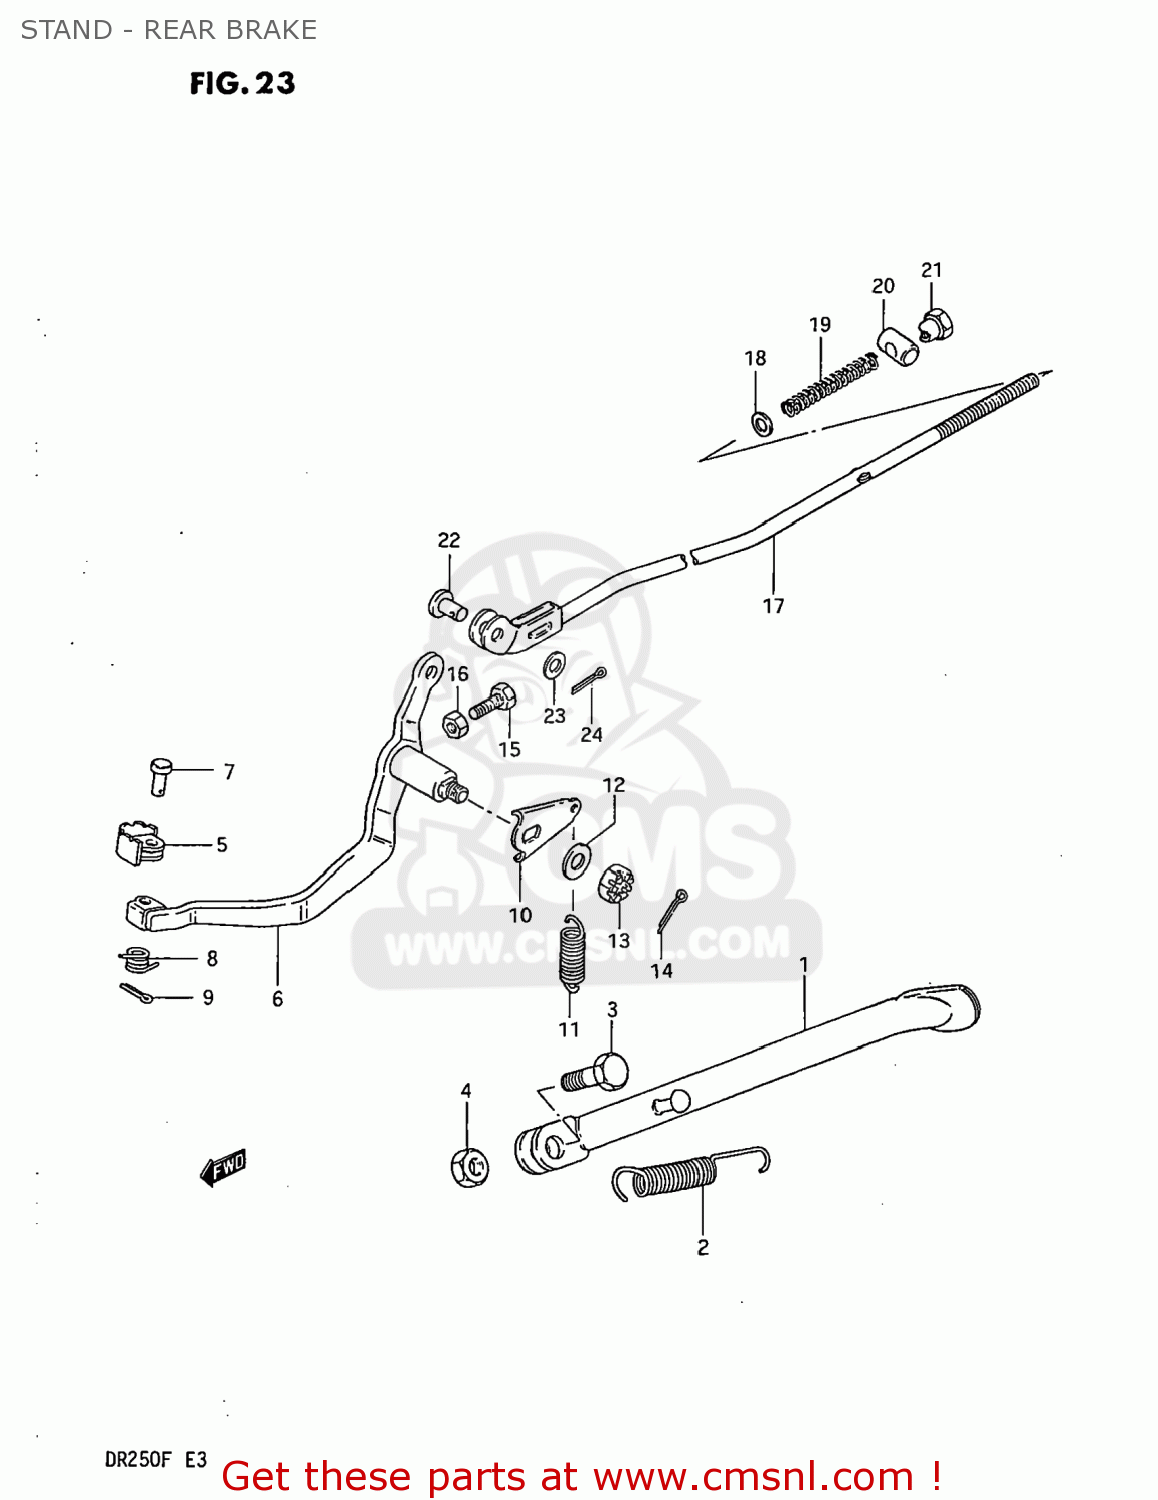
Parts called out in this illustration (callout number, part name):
1	STAND,SIDE
2	SPRING
3	BOLT(10X30)
4	NUT
5	PEDAL,BRAKE
6	ARM,BRAKE PEDAL ROD
7	PIN
8	SPRING
9	PIN
10	ARM,BRAKE RETURN SPRING
11	SPRING
12	WASHER
13	NUT 8MM
14	PIN 20X20
15	BOLT(6X23)
16	NUT
17	ROD ASSEMBLY,REAR BRAKE
18	WASHER
19	SPRING
20	PIN(11X18)
21	NUT (6MM)
22	PIN
23	WASHER
24	PIN 20X20
